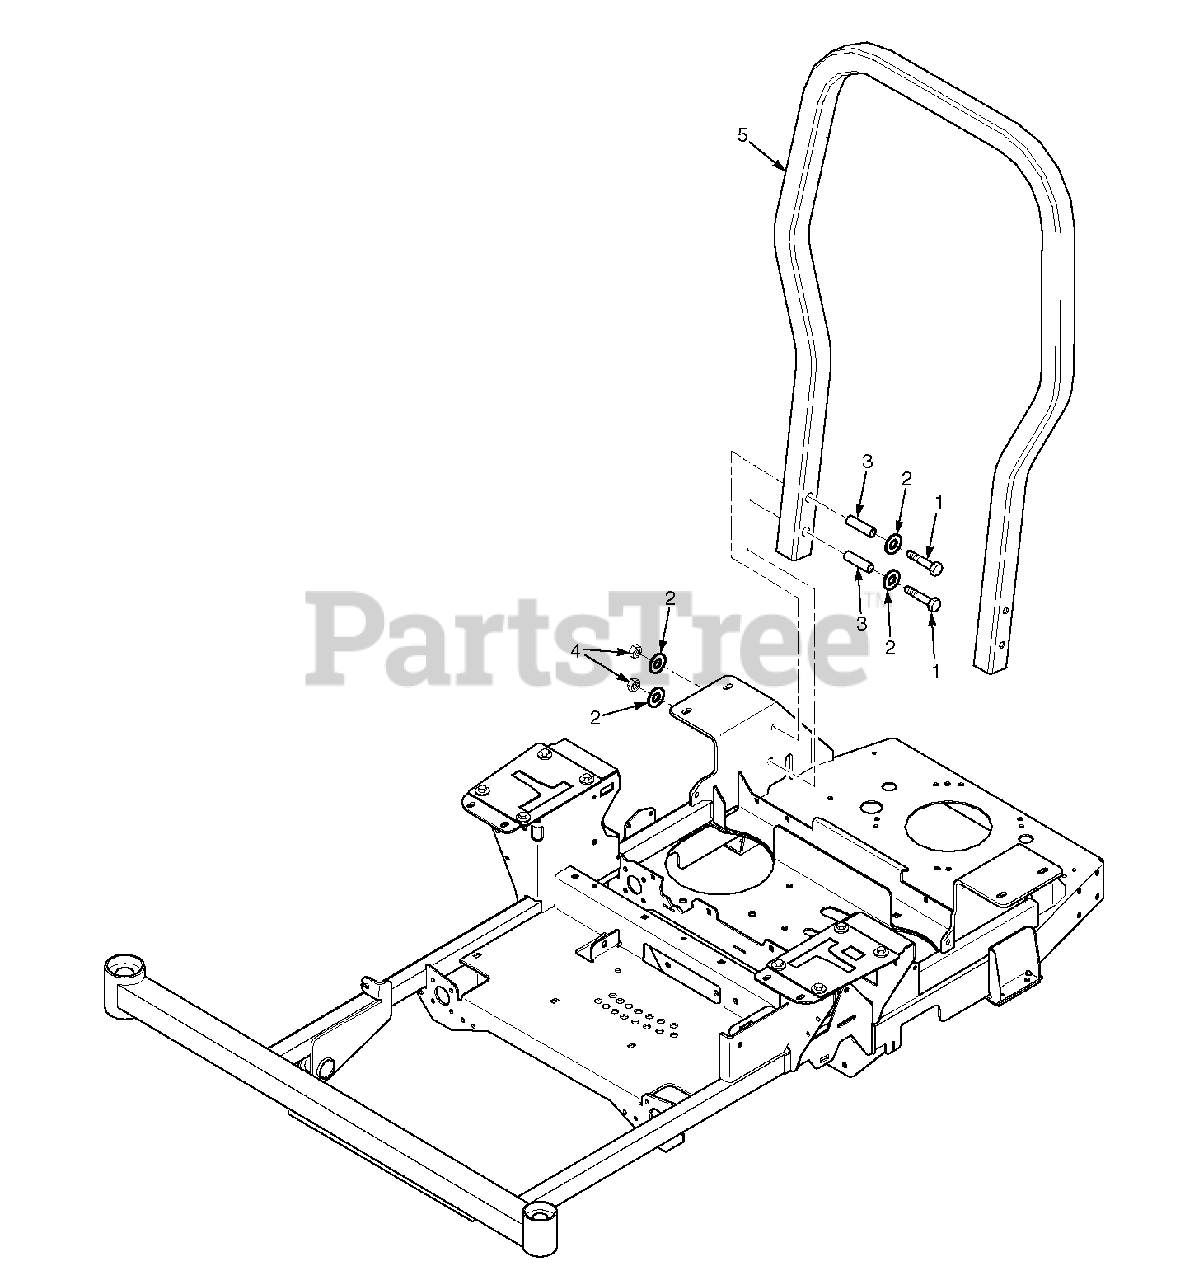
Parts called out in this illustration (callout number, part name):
1	Bolt, Hex Head 1/213 x 3-1/4" Gr. 8
2	Flatwasher, 1/2 - .562 x 1.375 x .109
3	Bushing, SFZ ROPS
4	Nut, Center Lock 1/2-13
5	ROPS, SFZ36
5	ROPS, SFZ48, SFZ52 & SFZ61
